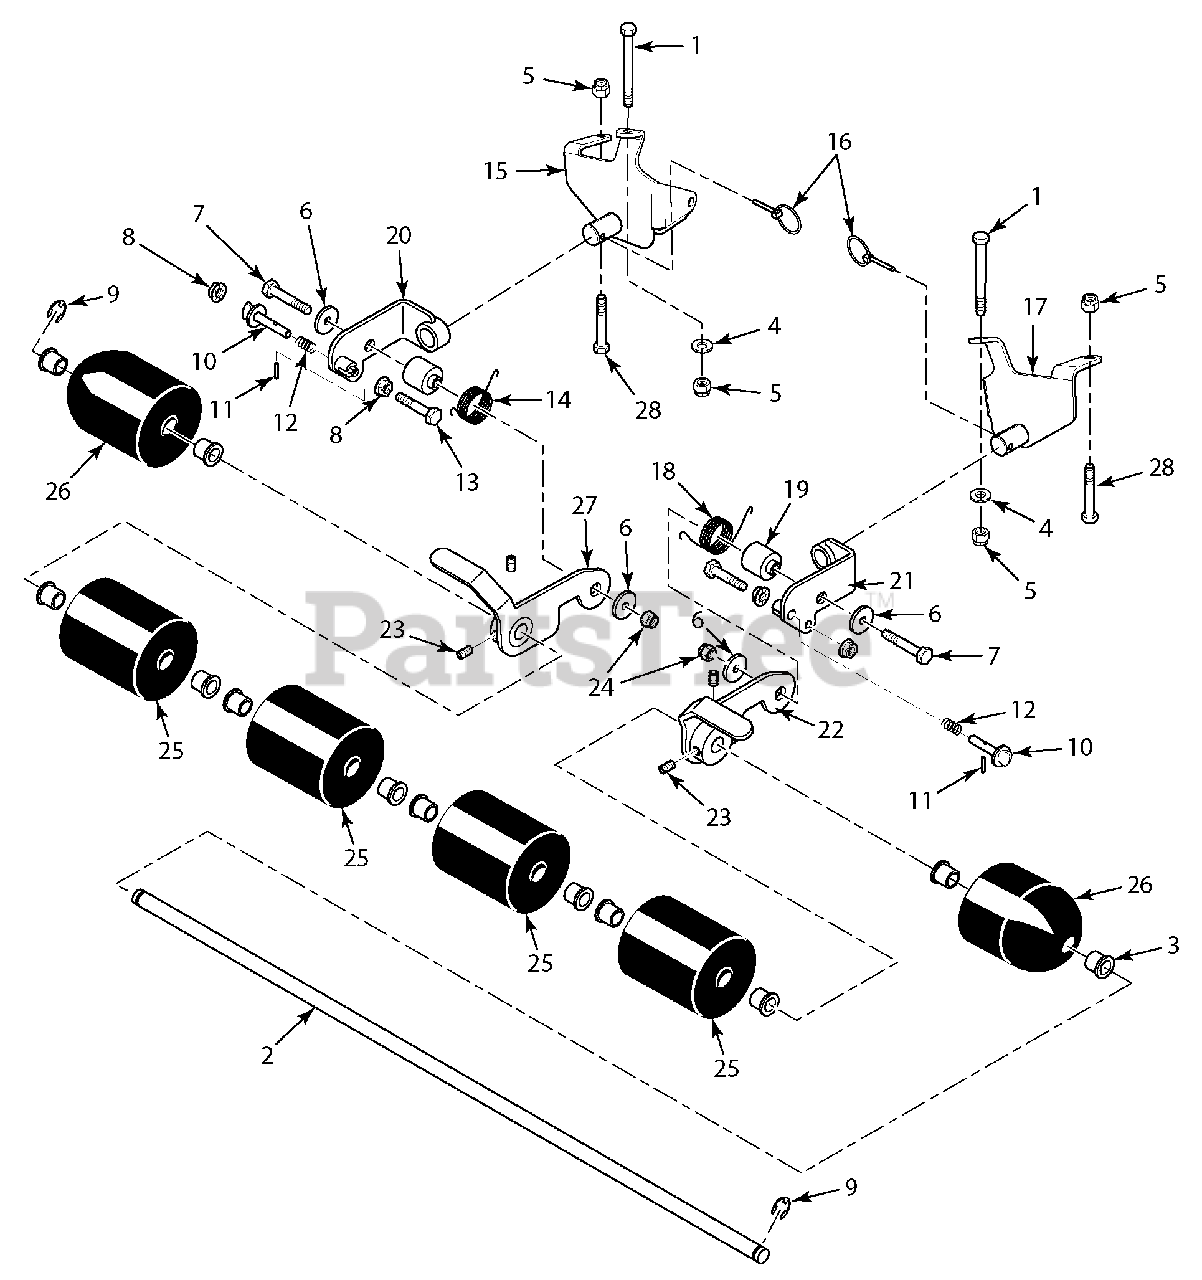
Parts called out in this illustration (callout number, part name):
1	Bolt, Hex Head 5/16-18 x 5-1/2"
2	Roller Shaft
3	Bushing, .752 Oilite
4	Flatwasher, 5/16-.378 x .875 x .083
5	Nut, Elastic Stop 5/16-18
6	Flatwasher, 3/8-.406 x 1-1/2" 7 Gauge
7	Bolt, Hex Head 3/8-16 x 2-3/4"
8	Nut, Serrated Flange 3/8-16
9	Retaining Ring, .750 External "E"
10	Pin, Lift Latch
11	Pin, Slotted Spring 5/32" x 7/8"
12	Spring, Lock Pin
13	Bolt, Hex Head 3/8-16 x 2-1/2"
14	Spring, Torsion LH
15	Mounting Bracket Weldment, LH
16	Quick Pin, .188 Dia.
17	Mounting Bracket Weldment, RH
18	Spring, Torsion RH
19	Hub, Striper
20	Pivot Weldment, LH
21	Pivot Weldment, RH
22	Hinge Weldment, RH
23	Set Screw, 3/8-16 x 1/2"
24	Nut, Elastic Stop 3/8-16
25	Roller Assembly
26	Roller Assembly, Striper End
27	Hinge Weldment, LH
28	Bolt, Hex Head 5/16-18 x 3-1/4"
